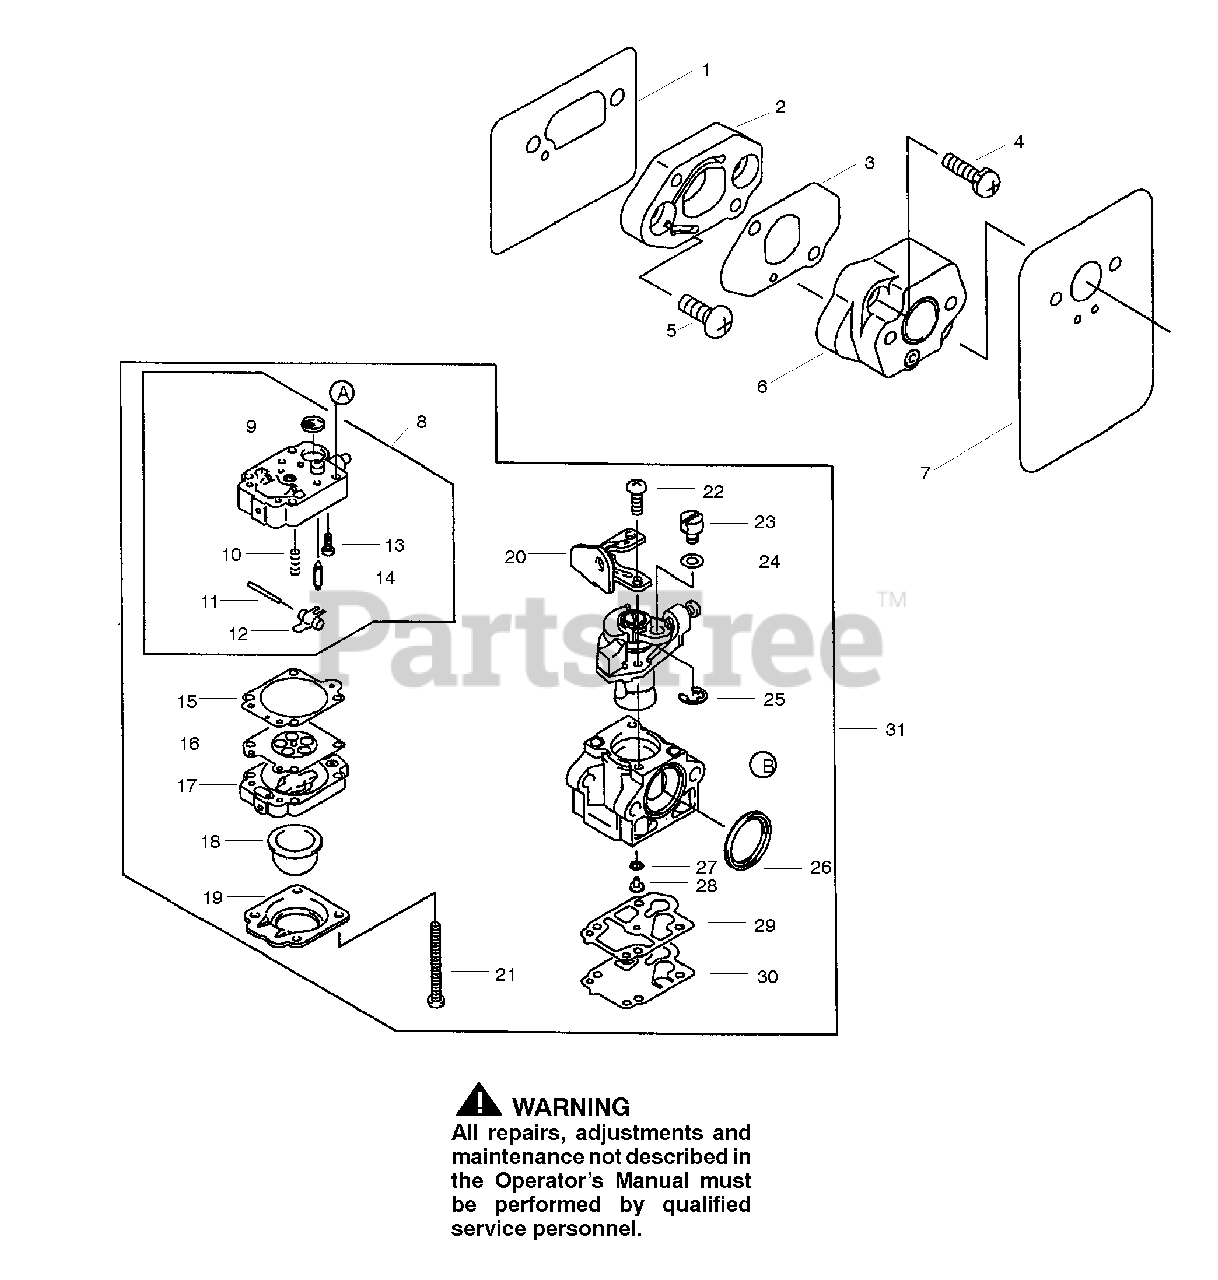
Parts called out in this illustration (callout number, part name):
1	Gasket-Insulator
4	Screw-Pan-WP
5	Screw-Pan
6	Insulator
7	Gasket
10	Spring
12	Lever
14	Valve-Float
16	Diaphragm
18	Pump-Priming
19	Cover-Primer Pump
22	Screw
23	Arm
24	Washer
25	Ring-Snap
28	Jet-Main #60
30	Diaphragm
31	Assy-Carburetor (WYK-106-108)
